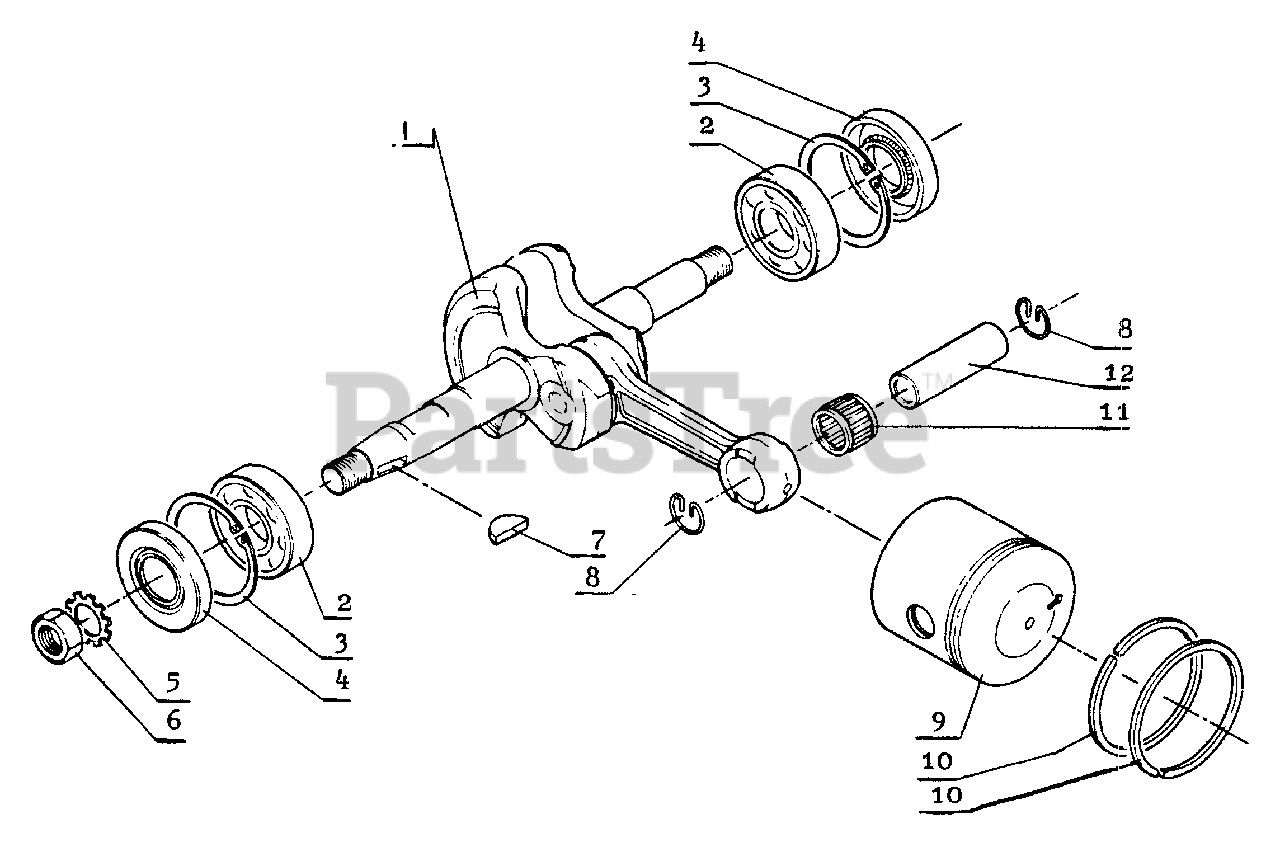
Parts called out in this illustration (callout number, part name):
1	CRANKSHAFT ASSY
2	BEARING, BALL - 6202
3	RING, RETAINING - 35
4	SEAL, OIL
5	WASHER - 10
7	KEY - 3X14
8	RING, RETAINING
9	PISTON
10	RING, PISTON
11	BEARING, NEEDLE
12	PIN, PISTON
